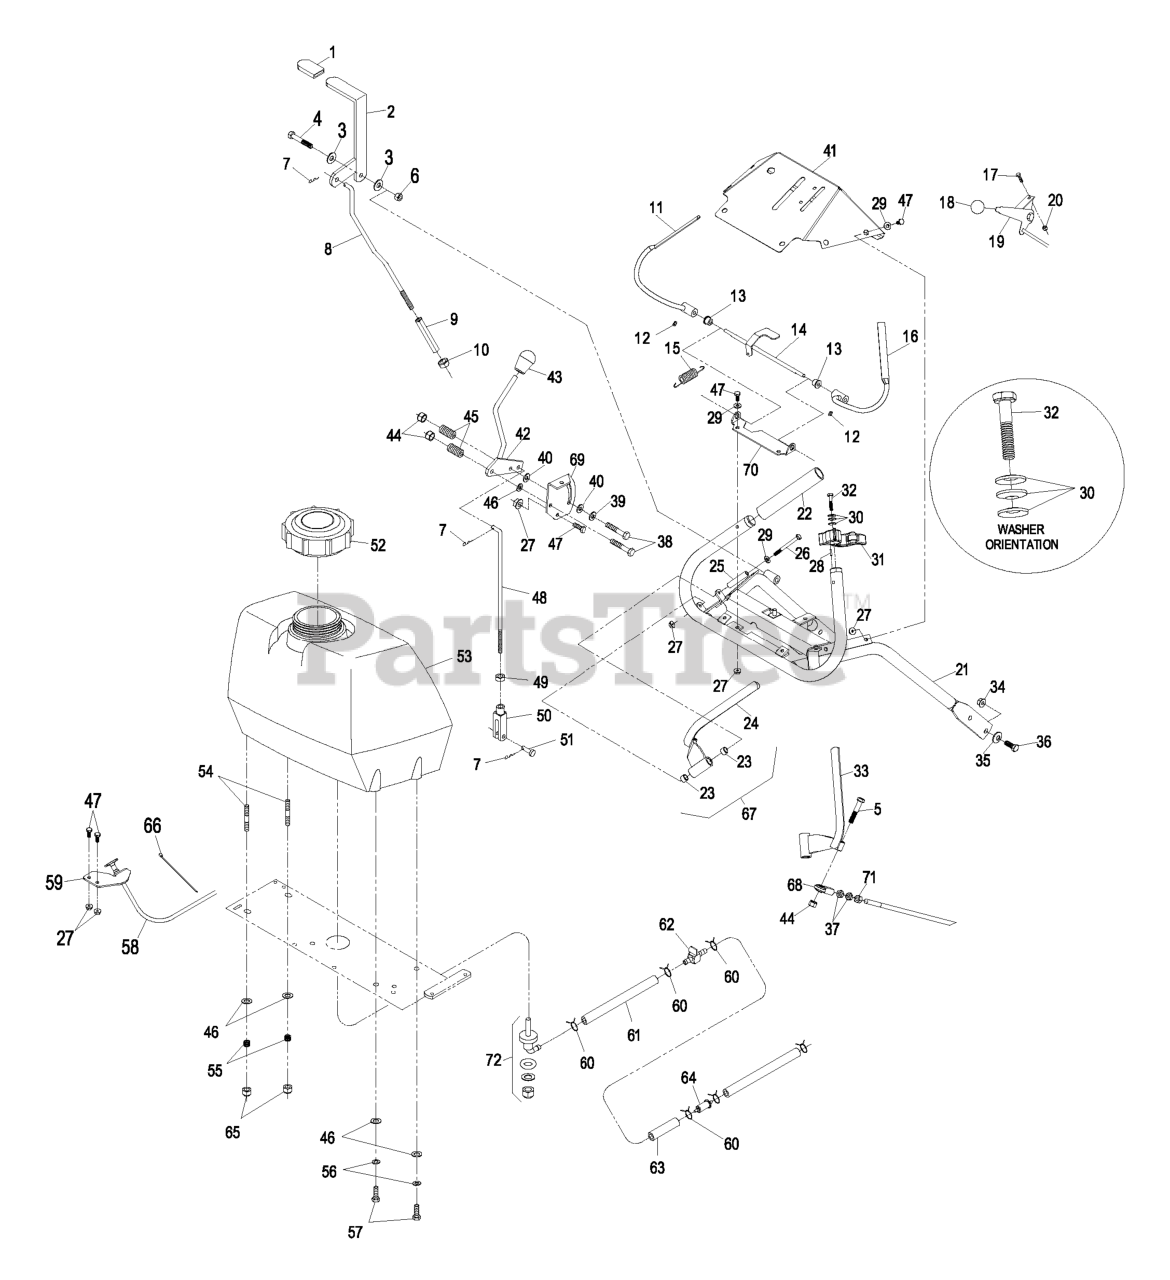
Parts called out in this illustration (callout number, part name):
1	GRIP-LEVER
3	WASHER-FLAT
4	SCREW-HH
5	SCREW-HH
6	NUT-LOCK, NI
7	PIN-COTTER
8	LINK,BLADE ENGAGE (PLTD)
9	TURNBUCKLE
10	NUT-HEX
12	SCREW-SET
13	BUSHING-NYLON
14	WLD,OPC LEVER AXLE
15	SPRING-EXTENSION
17	BOLT-CARR
18	KNOB-BALL
19	THROTTLE CABLE ASM
20	NUT-LOCK, NI
21	WLD,UPPER ECS HANDLE
22	GRIP-BAR, HANDLE
23	BUSHING-SLEEVE
25	BUSHING-LEVER, DRIVE
26	SCREW-HH
27	NUT-HF
29	WASHER-FLAT
30	WASHER-SPRING
31	ASM,LATCH RH THUMB
32	SCREW-HH
34	NUT-HHF, WHIZ
35	WASHER-BELLEVILLE
36	SCREW-HH
37	NUT-HJ
38	SCREW-HH
39	WASHER-FRICTION
40	WASHER-FRICTION
41	ASM,CONSOLE W/DECALS
43	KNOB, FE.LCKG. BLACK
44	NUT-LOCK, NI
45	SPRING-COMPRESSION
46	WASHER-PLAIN
47	SCREW-HH
48	ROD,SPEED CONTROL
49	NUT-JAM
50	YOKE-ADJUSTABLE
51	PIN-CLEVIS
52	CAP-FUEL, GAS
53	ASM,FUEL TANK W/B
54	STUD
55	SPRING-TANK, FUEL
56	WASHER-LOCK
57	SCREW-HH
58	CABLE-CHOKE
59	BRACKET-CABLE, CHOKE
61	HOSE-FUEL
62	VALVE-FUEL
63	HOSE-FUEL
64	Kawasaki Pn 41019-1055 Filter W/6" Fuel Line
65	NUT-LOCK, NI
66	TIE-CABLE
67	DRIVE LEVER-ASM, RH
68	JOINT-BALL, END
69	BRACKET,SHIFTER SLIDE (PL
70	BRACKET,OPC AXLE
71	NUT-HEX
72	FITTING-FUEL, BULKHEAD
